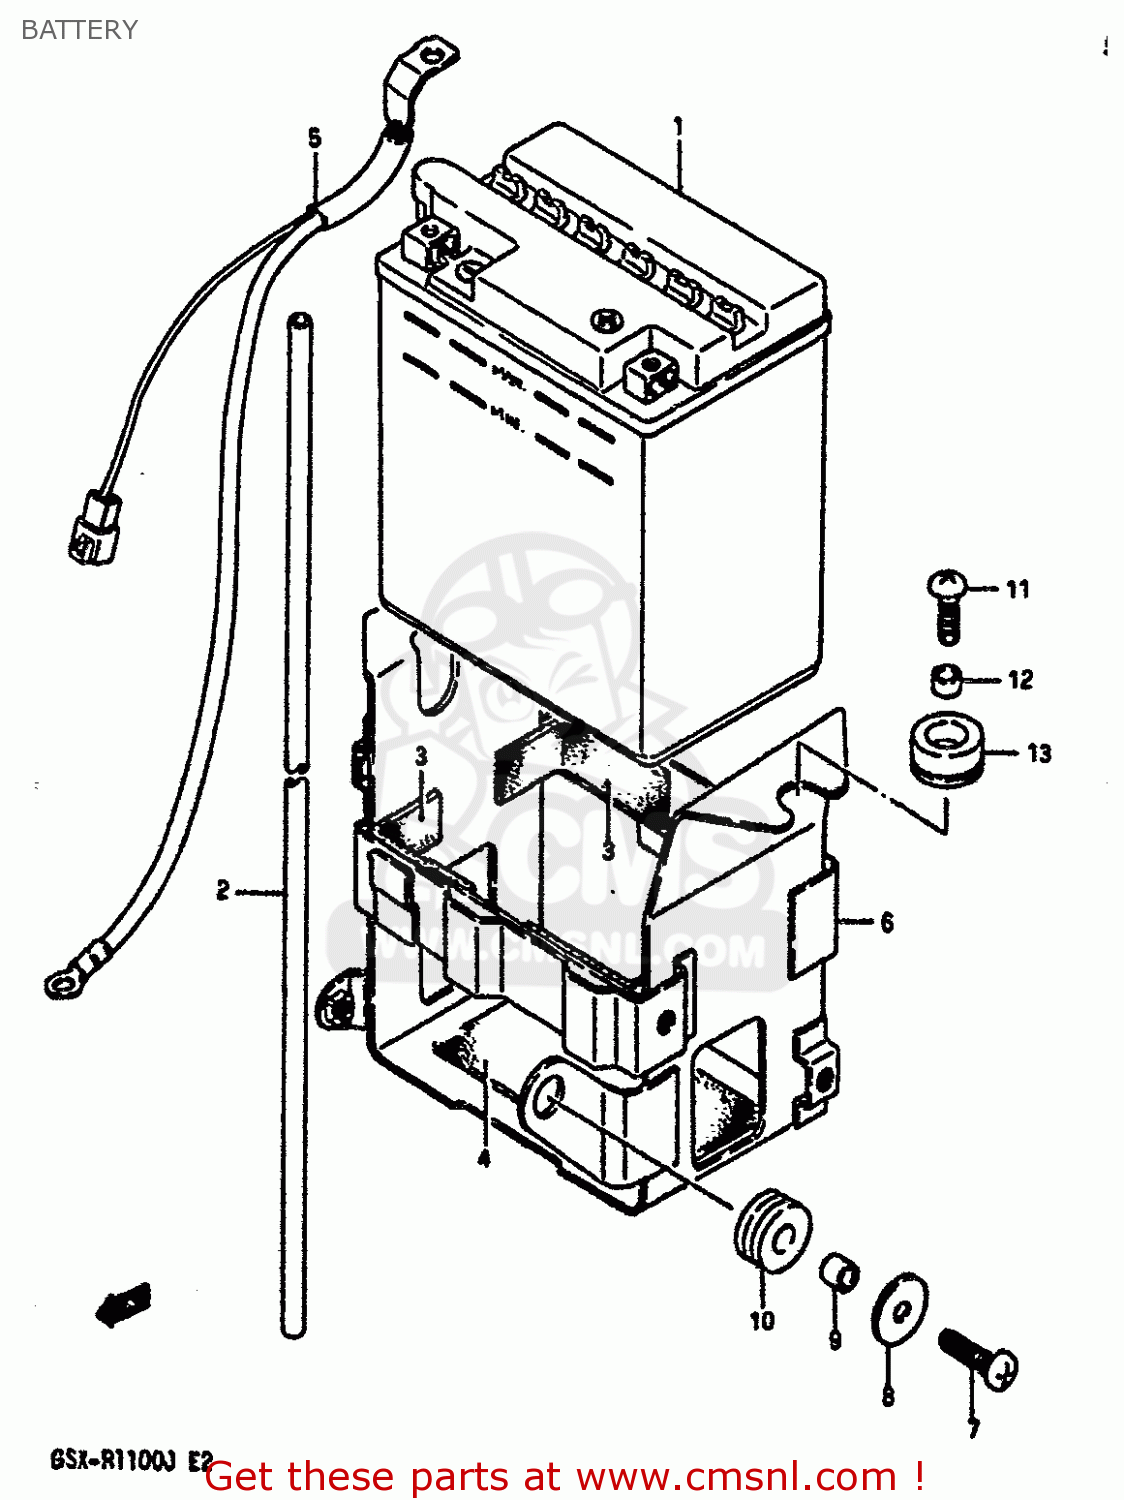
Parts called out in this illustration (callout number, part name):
1	BATTERY ASSY (12V)
2	HOSE,BATTERY EXHAUST
3	PROTECTOR,20X9
4	PROTECTOR(170X95X3.0)
5	WIRE,BATTERY MINUS LEAD
6	HOLDER,BATTERY
7	SCREW
8	WASHER
9	SPACER
10	CUSHION
11	SCREW
12	SPACER
13	CUSHION,HOLDER BATTERY UPR
